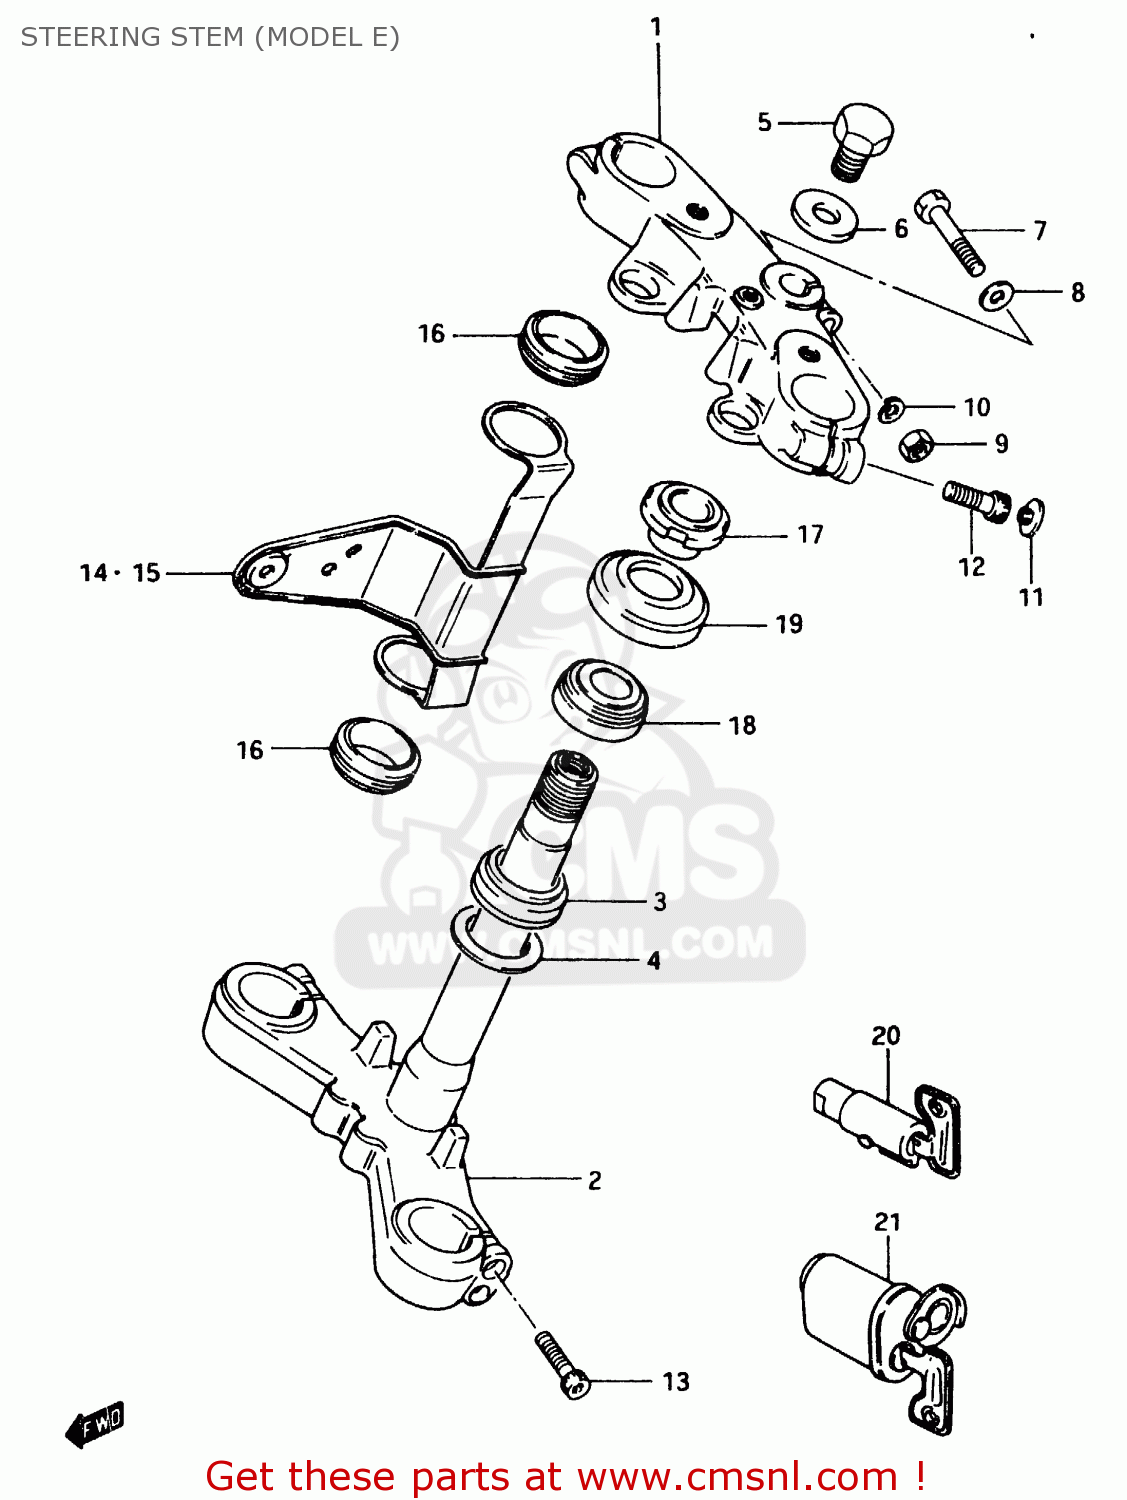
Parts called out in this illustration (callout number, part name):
1	HEAD,STEERING STEM
2	STEM,STEERING
3	BEARING
4	WASHER,THRUST
5	BOLT
6	WASHER,STEM HEAD
7	BOLT
8	WASHER
9	NUT 8MM
10	WASHER,LOCK,8.
11	CAP(OD:20)
12	NUT,STEM HEAD
13	BOLT 8X35
14	BRACKET, HEADLAMP RH (BLACK)
15	BRACKET, HEADLAMP LH (BLACK)
16	CUSHION,HEADLAMP BRACKET
17	NUT,STEERING STEM
18	TAPER,ROLLER BEARING
19	DUST SEAL,STEERING UPR
20	LOCK ASSEMBLY,STEERING (NEI
21	LOCK ASSY, STEERING (NEIMAN TYPE EXECUTE
